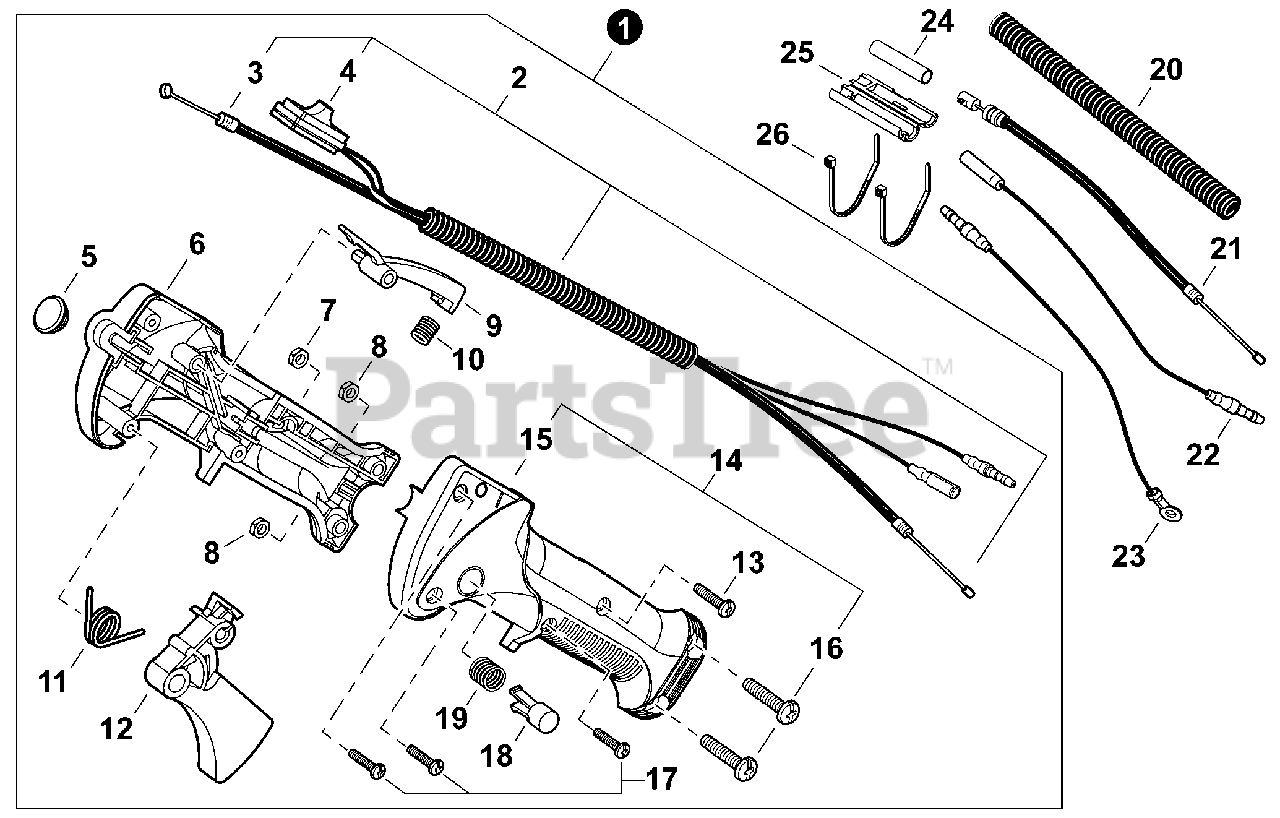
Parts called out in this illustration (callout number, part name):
1	THROTTLE CONTROL ASSY
2	CABLE ASSY, CONTROL
3	CABLE, THROTTLE
4	SWITCH, ON-OFF
5	PLUG, RUBBER
6	CONTROL HANDLE - RIGHT
7	NUT M4
8	NUT M5
9	LOCKOUT, THROTTLE
10	SPRING, COMPRESSION
11	SPRING, TORSION
12	TRIGGER, THROTTLE
13	SCREW M4x23
14	CONTROL HANDLE SET
15	CONTROL HANDLE - LEFT
16	SCREW M5x22
17	SCREW, TAPPING 4x16
18	BUTTON, THROTTLE LOCK
19	SPRING, COMPRESSION
20	TUBE, FLEXIBLE
21	CABLE, THROTTLE
22	LEAD - IGNITION
23	LEAD - GROUND
24	SLEEVE
25	CAP, DUST
26	TIE, CABLE
